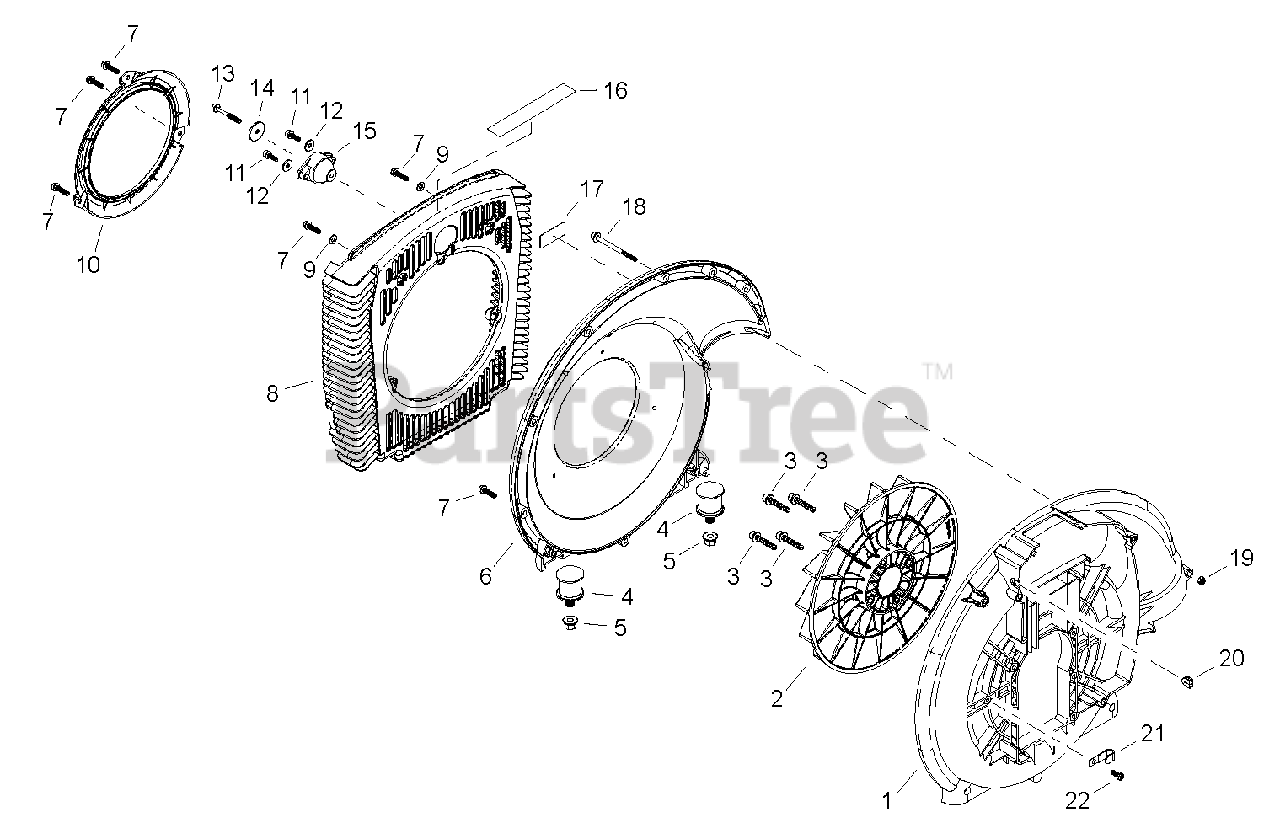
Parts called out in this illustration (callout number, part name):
1	COVER, FAN - OUTER
2	IMPELLER
3	SCREW - 6X35
4	CUSHION
5	NUT - 6 -- FLANGE
6	COVER, FAN - INNER
7	BOLT - 5X20
8	COVER, INTAKE
9	WASHER - 5
10	FUNNEL
11	SCREW - 5X16
12	COLLAR
13	BOLT - 5 -- TAPPING
14	COLLAR - 25X5.5X2
15	CUSHION
16	LABEL - CAUTION
17	LABEL - CAUTION
18	SCREW - 5X70
19	NUT - 5
20	GROMMET
21	CLAMP
22	SCREW - 5X14 -- TAPPING
